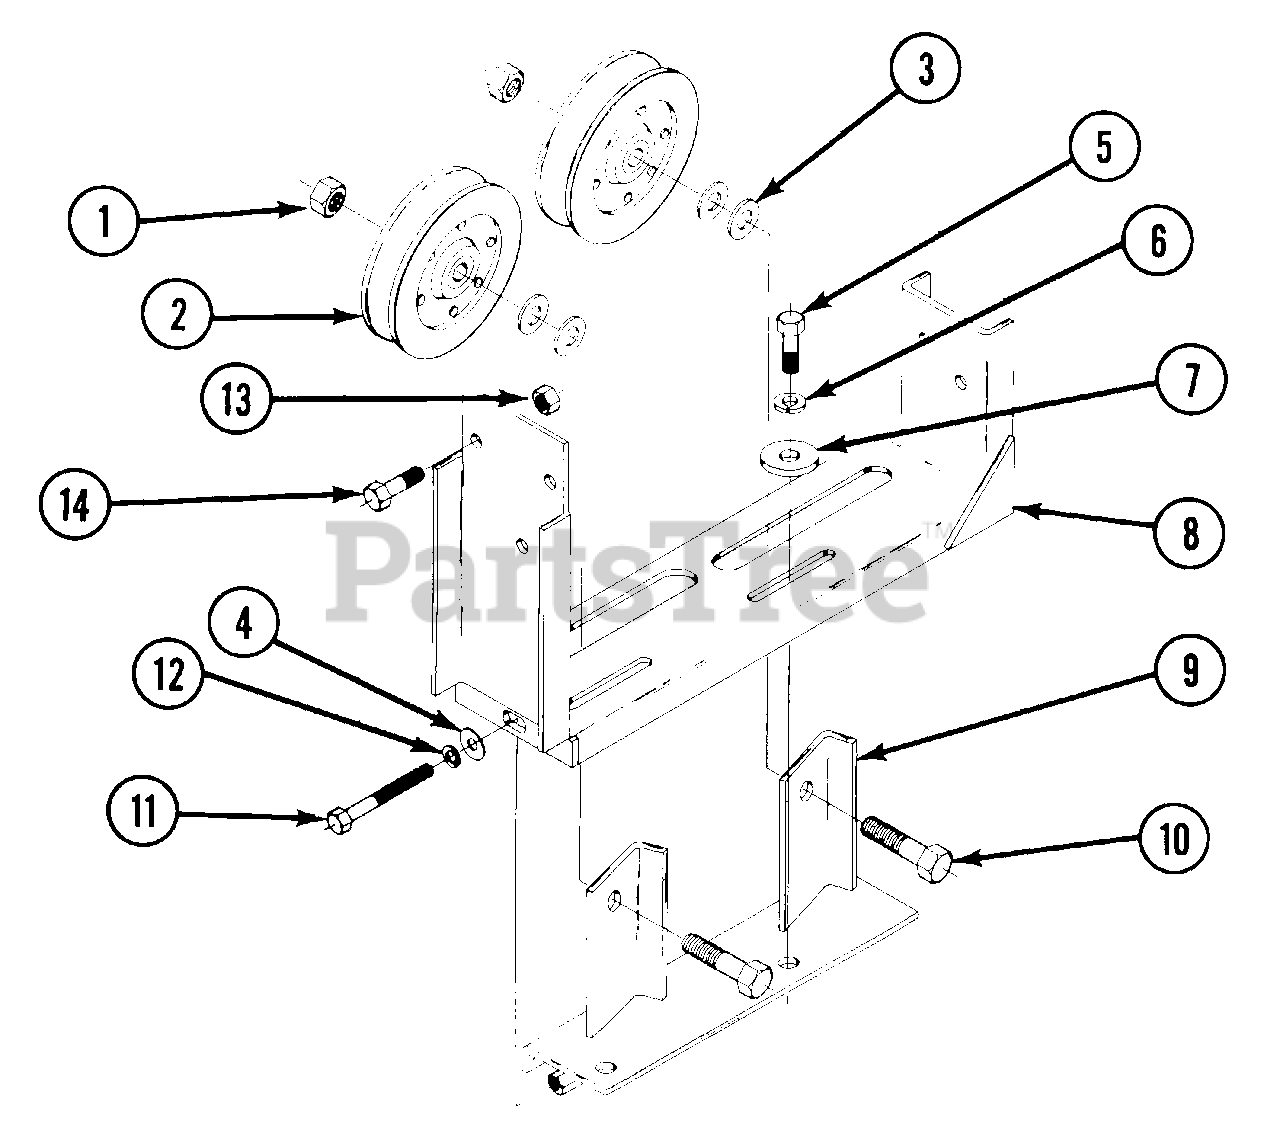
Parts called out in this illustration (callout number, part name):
1	LOCKNUT, HEX, 1/2-13, W/NYLOC
2	IDLER PULLEYS V, 4-3/8 OD, 1/2 BORE
3	WASHER 1/2 STD, FLAT
4	WASHER, 5/16 STD, FLAT
5	CAPSCREW, HEX, 3/8-16 X 1, GRADE 5
6	LOCKWASHER, 3/8 HEAVY, SPLIT SPRING
7	WASHER, .406 ID X 1.25 OD X .168 THK
8	MULE DRIVE IDLER MOUNT WELDMENT
9	SLIDE PLATE WELDMENT
10	CAPSCREW, HEX, 1/2-13 X 2, GRADE 5
11	CAPSCREW, HEX, 5/16-18 X 2-1/2, GRADE 5
12	LOCKWASHER, 5/16 HEAVY, SPLIT SPRING
13	LOCKNUT, HEX, 3/8-16, W/NYLOC
14	CAPSCREW, HEX, 3/8-16 X 1, GRADE 5
